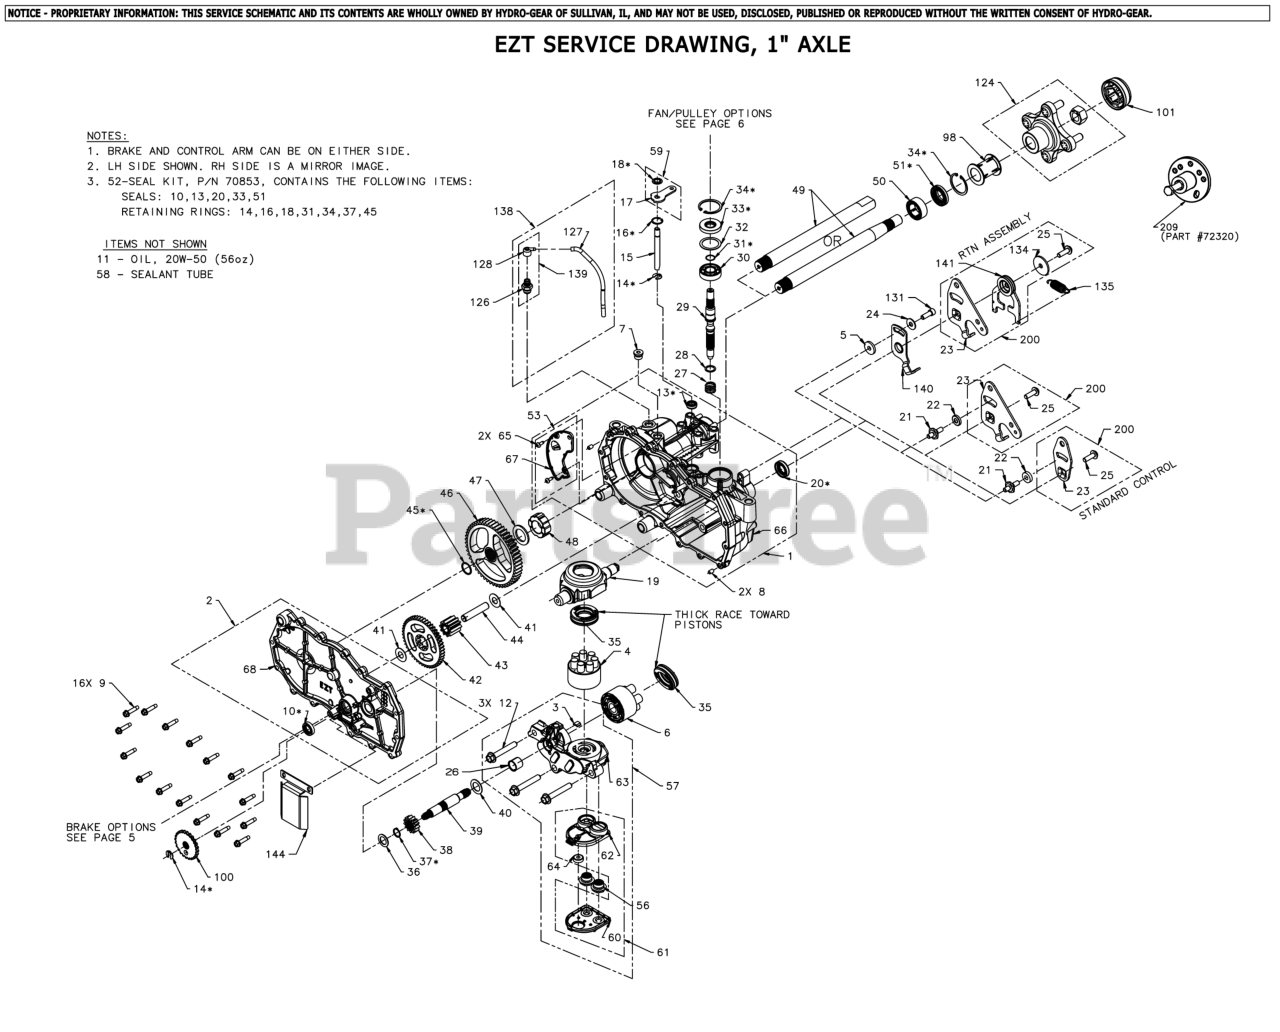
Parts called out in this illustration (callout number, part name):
4	ASSY, BLOCK 7 PISTON
6	KIT, 10 CC BLOCK
9	SCREW,HEX WASHER 1/4-20X1.125
11	FLUID, HYDRO 20W50 QT
15	ROD, BYPASS
19	TRUNNION, SWASHPLATE
27	SPRING. BLOCK
28	WASHER. THRUST .59 X .79 X .04
29	SHAFT, INPUT
30	BRG, BALL 17X40X12
32	WASHER 1.23X1.56X.04
35	BEARING. THRUST 30 X 52 X 13
36	WASHER .63X1.0X.05
38	GEAR, 13T PINNION
39	SHAFT, MOTOR
40	WASHER .71 X 1.16 X .04
41	WASHER .5X1.0X.032
42	GEAR, 10T/48T
43	GEAR, 10T JACKSHAFT
44	JACK SHAFT (PIN)
52	KIT, SEALS AND RETAINING
53	KIT, EXPANSION PLATE LH
58	SEALANT TUBE 10.1OZ.
59	KIT, BYPASS ARM
61	KIT, FILTER
100	DISC, COG BRAKE
101	CAP, AXLE
124	KIT, HUB 4 BOLT
135	SPRING, EXTENSION
140	ARM, NEUTRAL LEFT
209	HUB PULLER 5 BLT
